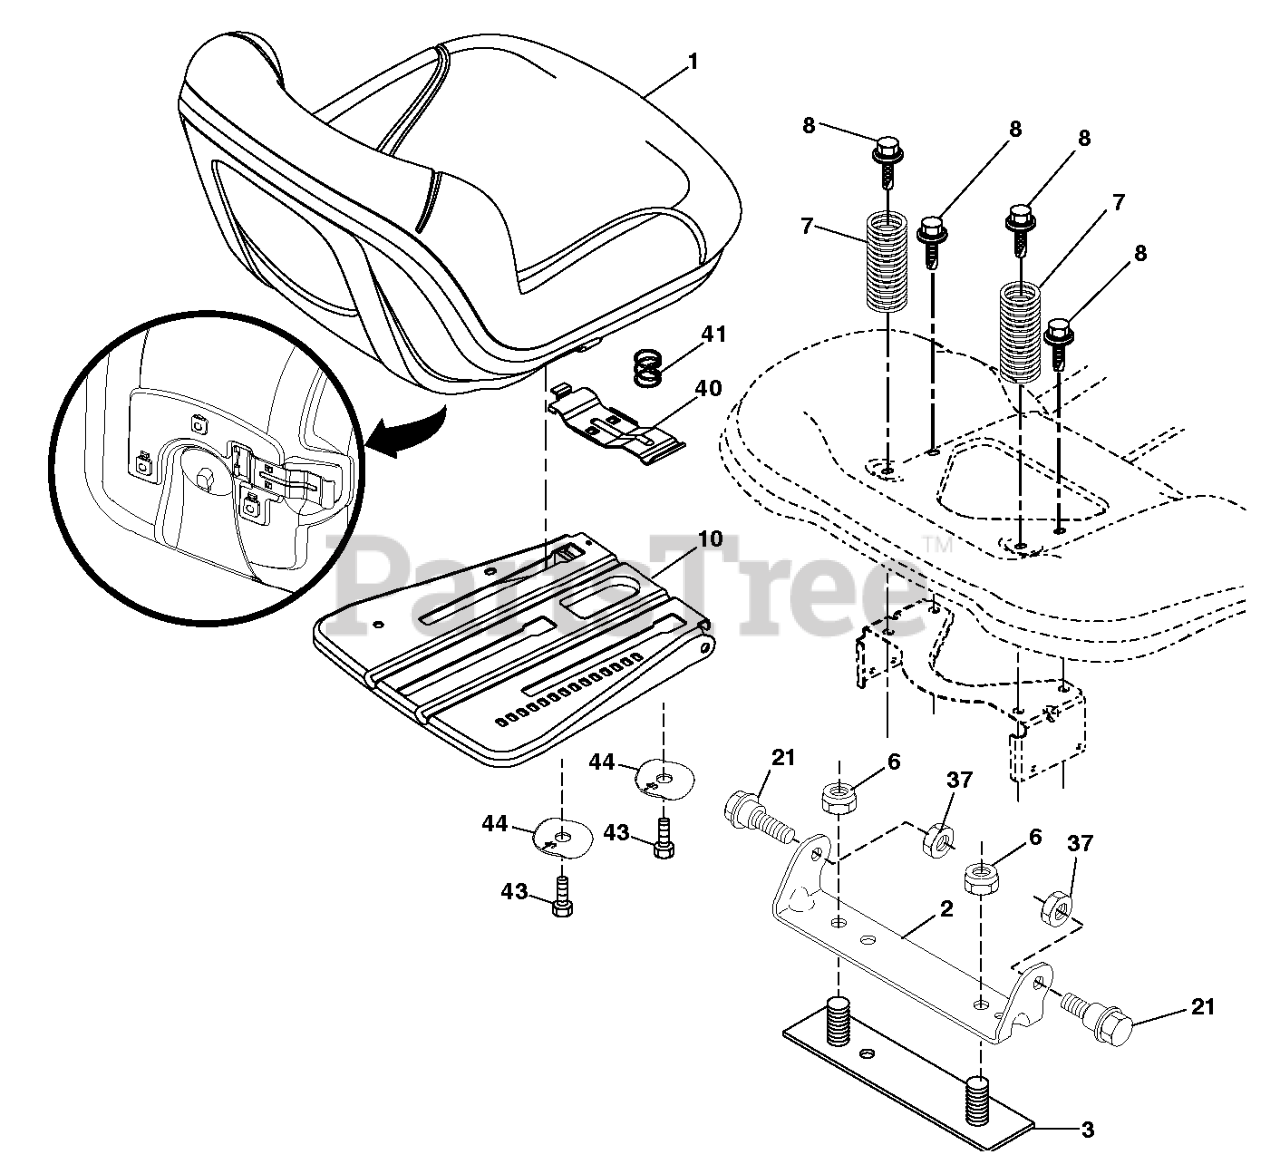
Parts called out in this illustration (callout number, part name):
1	SEAT.TH110.HUSQ.TEX.GREY
1	SEAT.TH130.GREY.HUSQ.TEX
2	BRKT.PIVOT.FENDER
3	STRAP
6	NUT
7	SPRING COMPRESSION
7	SPRING.COMPRESS.SEAT.TAPERED
8	BOLT.5/16-18UNCX3/4 W/SEMS.BLK
10	PLATE SEAT; SLIDE; 3PT BLACK;
21	BOLT.5/16-18X5/8.SHOULDER
37	Nuts
37	Hardware
41	SPRING.LATCH.SEAT.TEX
44	WASHER.WINGED.3/8ID.1.5OD
